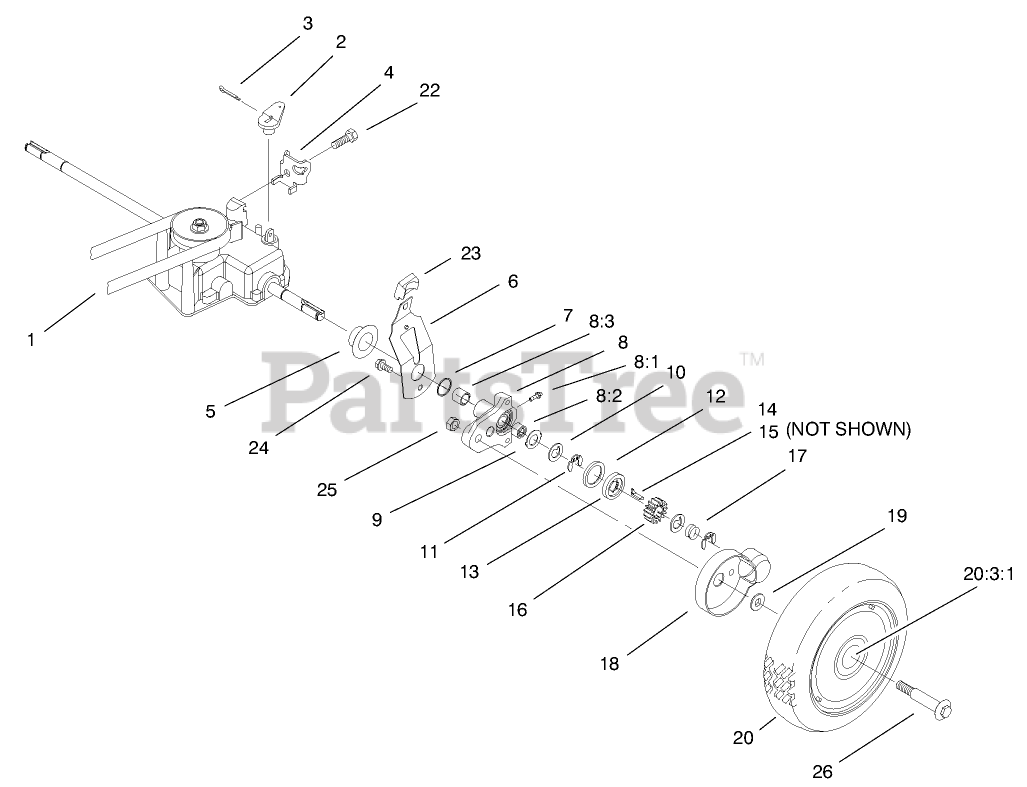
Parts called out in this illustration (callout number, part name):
1	V-BELT
2	LEVER-SHIFT
3	PIN-COTTER
4	CLAMP-CABLE
5	CAP-END
6	SPRING ARM ASM
7	O-RING
8	PIVOT ARM ASM
8:1	FITTING-GREASE
8:3	BUSHING
9	WASHER-ARM, PIVOT
10	WASHER-THRUST, KEYED
11	RING-RETAINING,CLIP
12	RING-FRICTION
13	WASHER-CLUTCH
14	KEY-ROCKING, LH
15	KEY-ROCKING, RH
16	GEAR-PINION
17	SPRING-COMPRESSION
18	COVER-WHEEL
19	SPACER-COVER, WHEEL
20	WHEEL AND TIRE ASM
20	WHEEL TIRE ASM (SP)
20:3	Wheel and Tire ASM
20:3:1	BUSHING
22	SCREW-HWHTF
23	KNOB-ARM
24	SCREW-HWH
25	NUT-LOCK
25	LOCKNUT
26	Bolt-Wheel (Serial No. 9900001-9900102)
